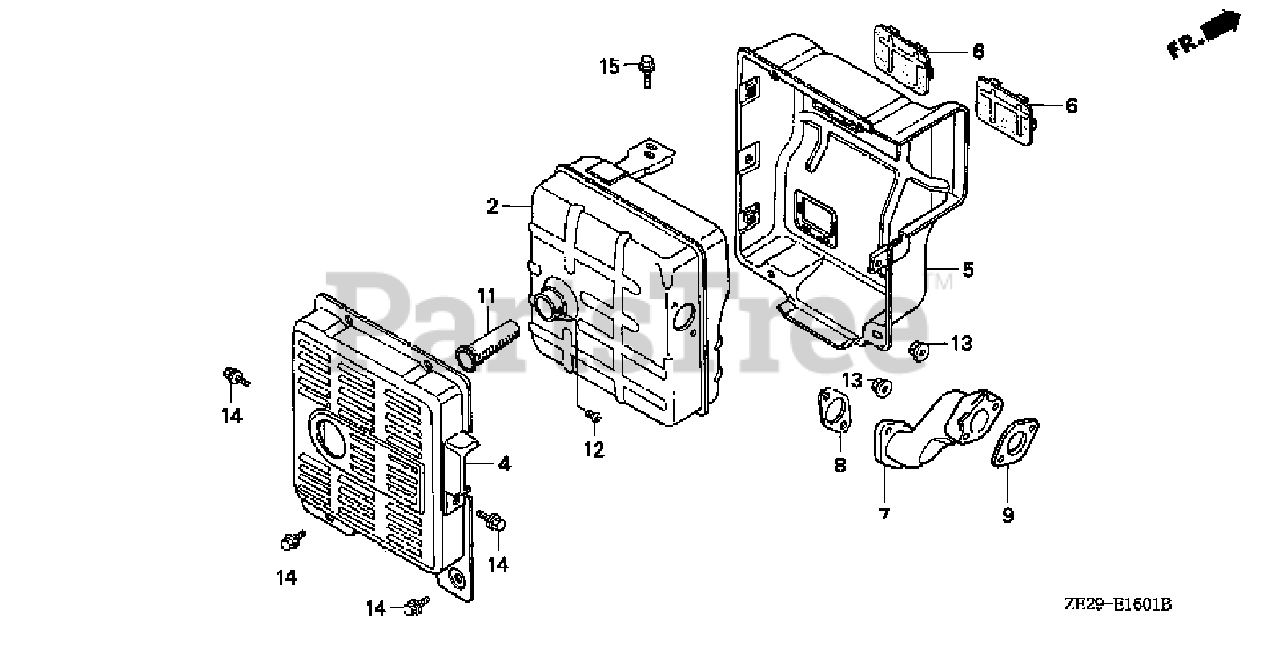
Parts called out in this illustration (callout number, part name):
2	MUFFLER (DENYO)
4	PROTECTOR, MUFFLER (OUTER)
5	PROTECTOR, MUFFLER (INNER)
6	SEAL, MUFFLER PROTECTOR
7	PIPE, EX.
8	GASKET, EX. PIPE
9	GASKET, EX. PIPE
9	GASKET, EX. PIPE (WACKER)
11	ARRESTER, SPARK
12	SCREW, TAPPING (4X8)
13	NUT, FLANGE (8MM)
14	BOLT, FLANGE (6X10)
15	BOLT, FLANGE (8X20)
